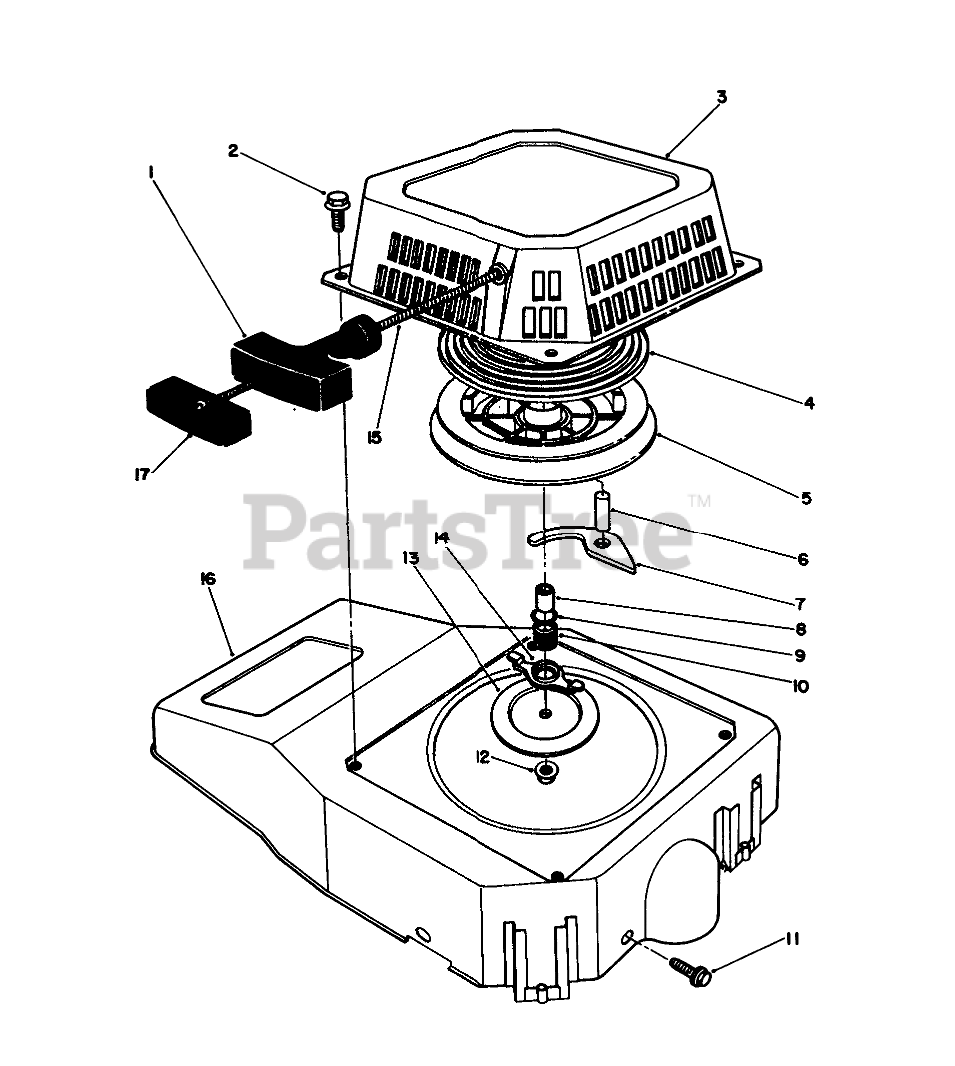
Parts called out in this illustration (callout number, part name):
1	HANDLE
2	SCREW-HHF
3	Case-Recoil
4	SPRING
8	Spacer
9	WASHER
10	Spring-Friction
13	PLATE
14	Guide-Paw
15	ROPE-STARTER
16	SHROUD
17	RETAINER HANDLE
